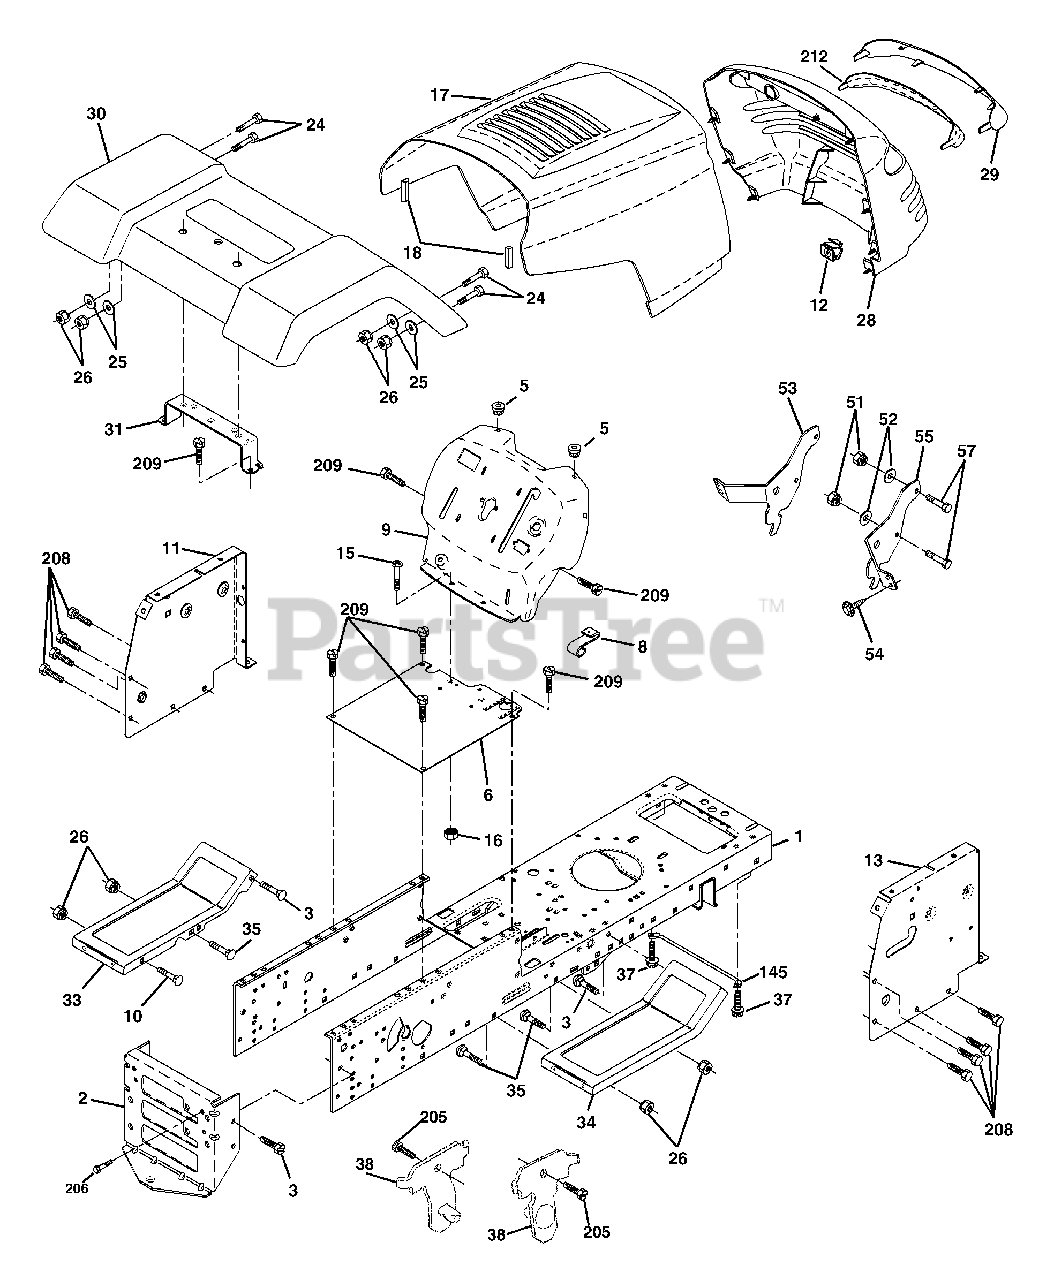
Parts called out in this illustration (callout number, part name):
1	Chassis
2	Drawbar
3	Screw 3/8-16 x 3/4
5	Bumper Hood/Dash
6	Saddle Slkscr Flt LT
8	Clip Retainer Slide-On
9	Dash
10	Bolt Rdhd Sqnk 3/8-16unc X 1
11	Panel Dash LH
12	Clip Tinnerman Grille P/L
13	Panel Slkscr Dash RH
15	Screw Mach TRHD 5/16-18 unc x 3/4
16	Nut Keps 5/16-18 Unc
17	Hood Asm
18	Bumper Hood
24	Bolt Fin Hex 3/8-16 unc x 1 Gr. 5
25	Washer 13/32 X 13/16 x 12 Ga
26	Nut Hex Lock W/Ins. 3/8-16 Unc
28	Grille/Lens Asm
29	Lens Headlight Bar Clear
31	Bracket Fender Repl 109873x
33	Footrest Pnt Lh
34	Footrest Pnt Rh
35	Bolt Rdhd Sht Sqnk 3/8-16 x 3/4
37	Screw Thdrol 5/16-18 x 1/2
38	Bracket Asm Pivot Mower Rear
51	Nut Lock Hex w/Ins 1/4-20
52	Washer 9/32 x 7/8 x 16 Ga.
53	Bracket, Grille LH
54	Screw
55	Bracket, Grille RH
57	Bolt Hex 1/4-20 x 3/4
145	Rod Pivot Chassis/Hood
205	Screw Thdrol 3/8-16 x 1/2
206	Bolt Shoulder 5/16-18
208	Screw thdrol 3/8-16 x 1/2
209	Screw Hex Wsh Thdrol 3/8-16
212	Insert Lens Reflective
